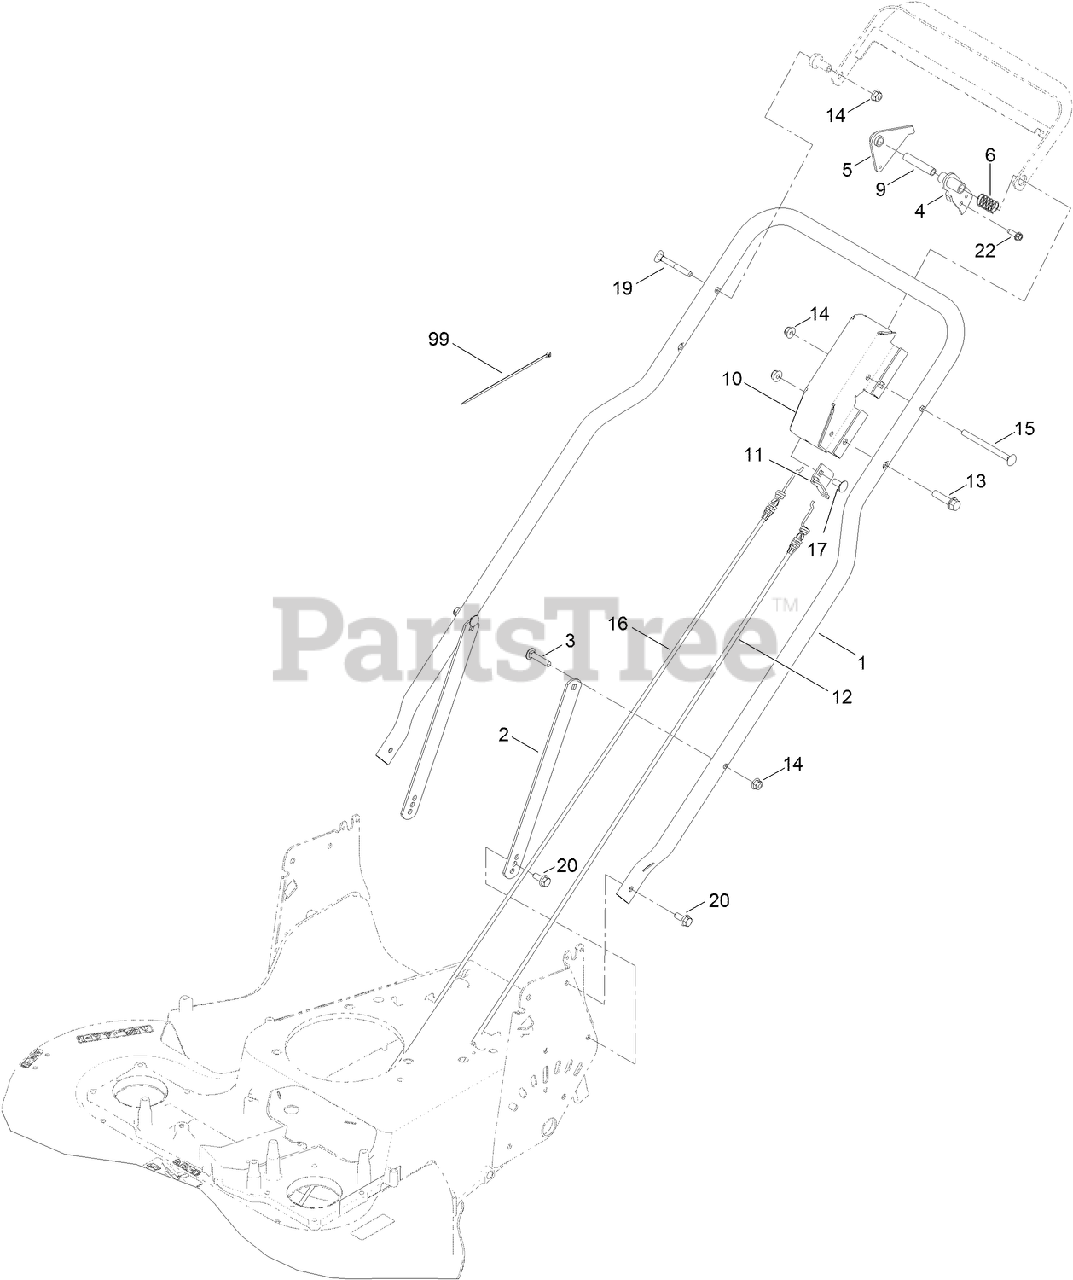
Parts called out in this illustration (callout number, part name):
2	SUPPORT-HANDLE
3	BOLT-CARR
4	BBC LEVER ASM
5	LEVER-TRACTION
6	SPRING-CONTROL
9	SPACER-BRACKET, CONTROL
10	BRACKET-CONTROL
11	BRACKET
12	CABLE-BRAKE
13	SCREW-HWH
14	NUT-HF, NI
15	SCREW-CARR
16	CABLE-TRACTION
17	SCREW-CARR
19	SCREW
20	SCREW-HHF
22	SCREW-HWHTF
99	TIE-CABLE
